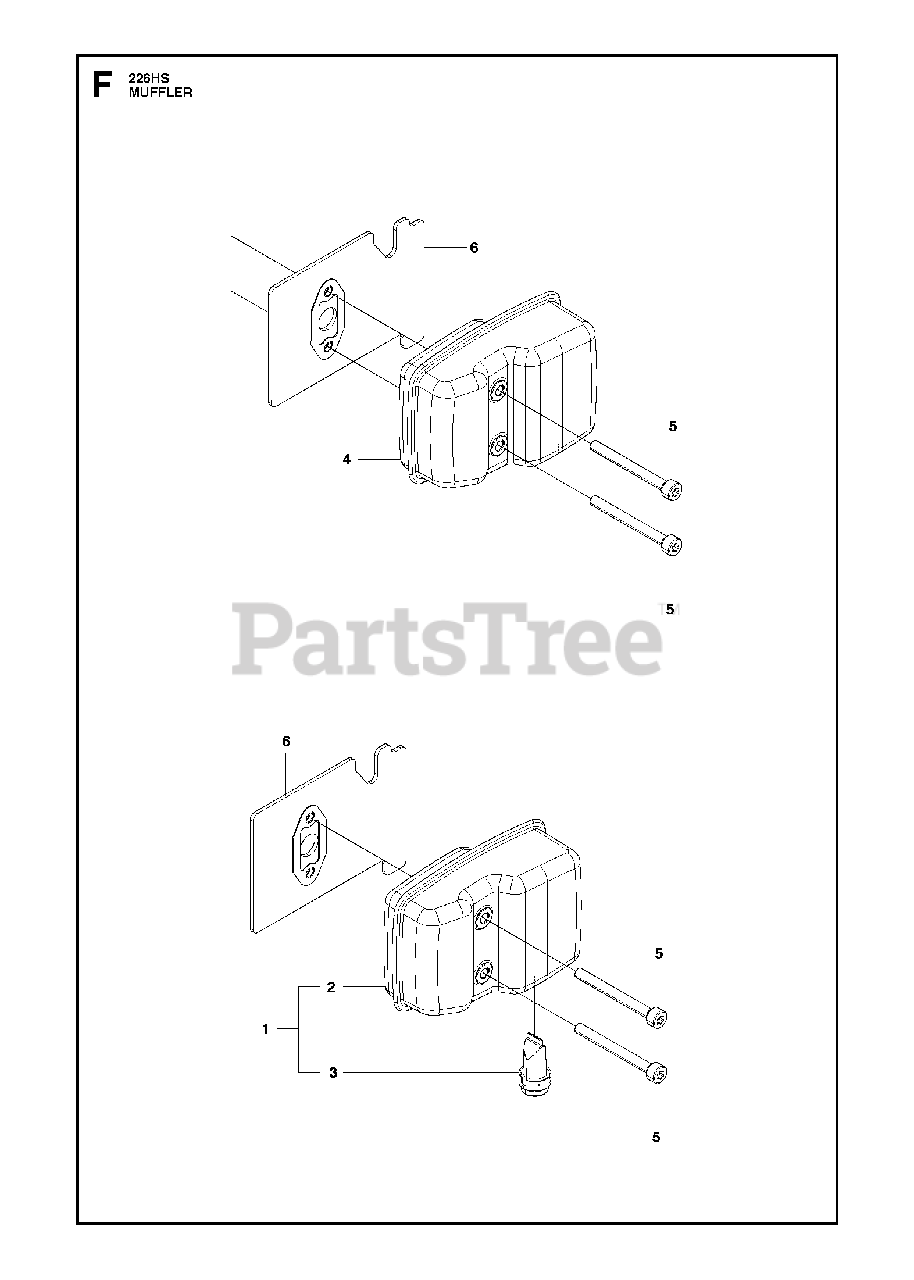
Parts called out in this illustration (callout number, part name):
1	MUFFLER
2	RP MUFFLER
3	ARRESTER
4	MUFFLER
